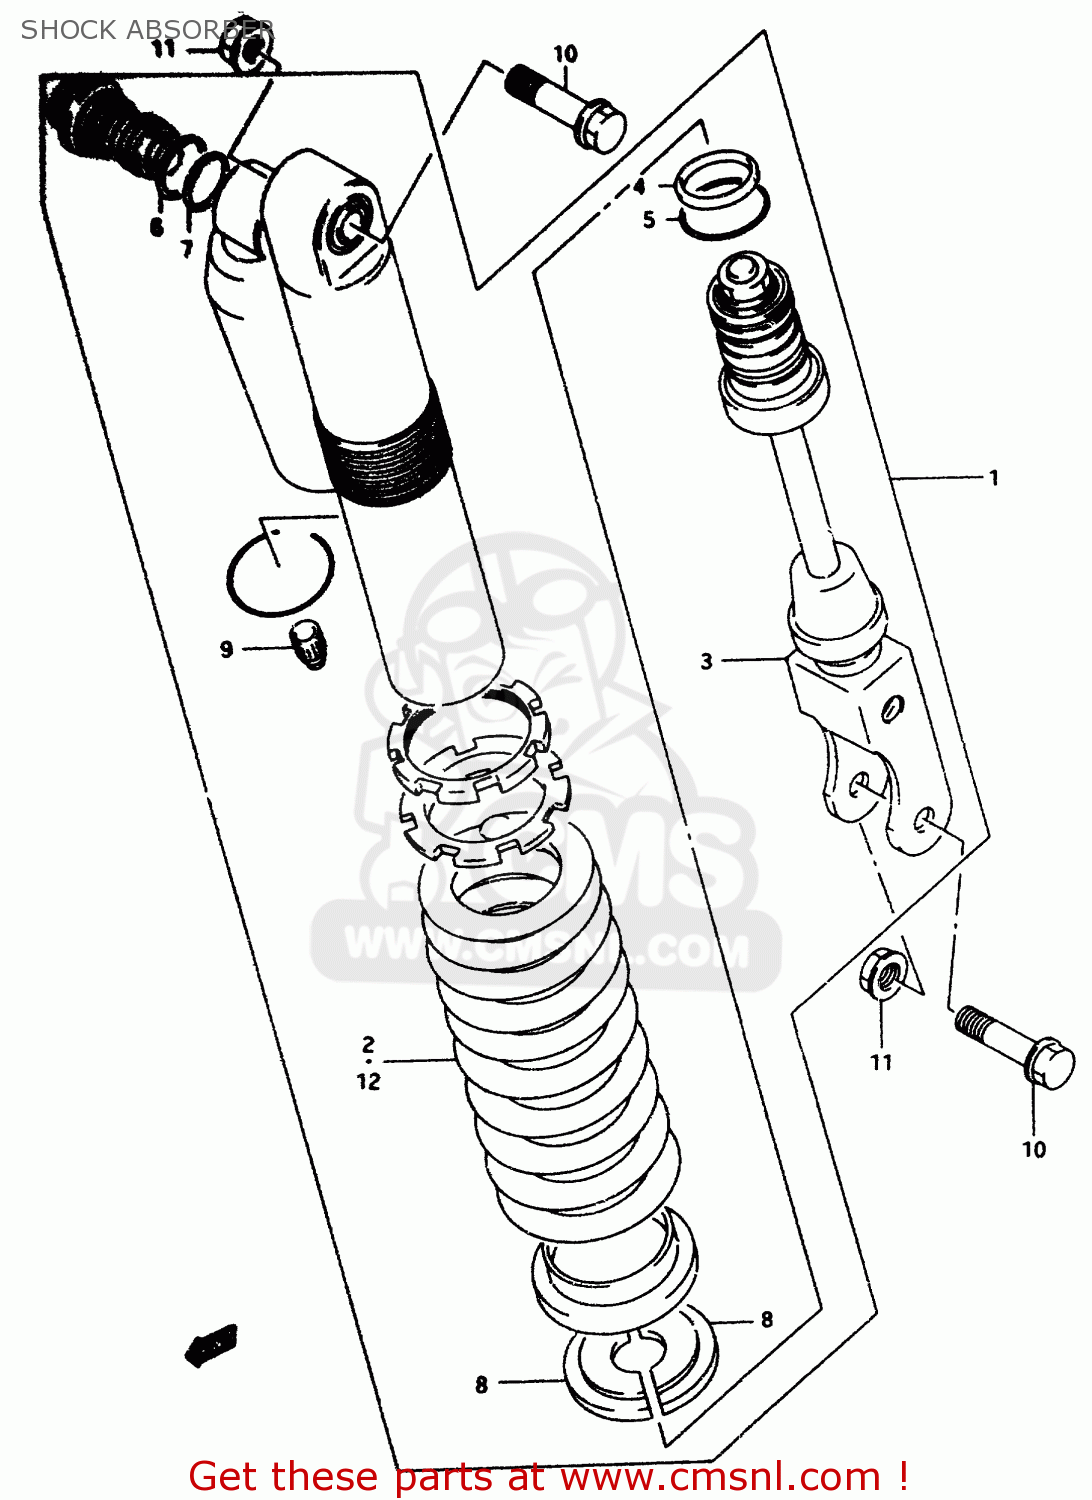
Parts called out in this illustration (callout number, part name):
1	ABSORBER ASSY,REAR SHOCK (PURPLE)
2	SPRING
3	ROD,PISTON
4	O RING
5	RING,PISTON ROD STOPPER
6	O RING
7	O-RING,FORK BOLT,LOWER
8	SEAT,SPRING STOPPER
9	CAP
10	BOLT,RR CUSHION ROD UPR
11	NUT
12	SPRING(SOFT)
